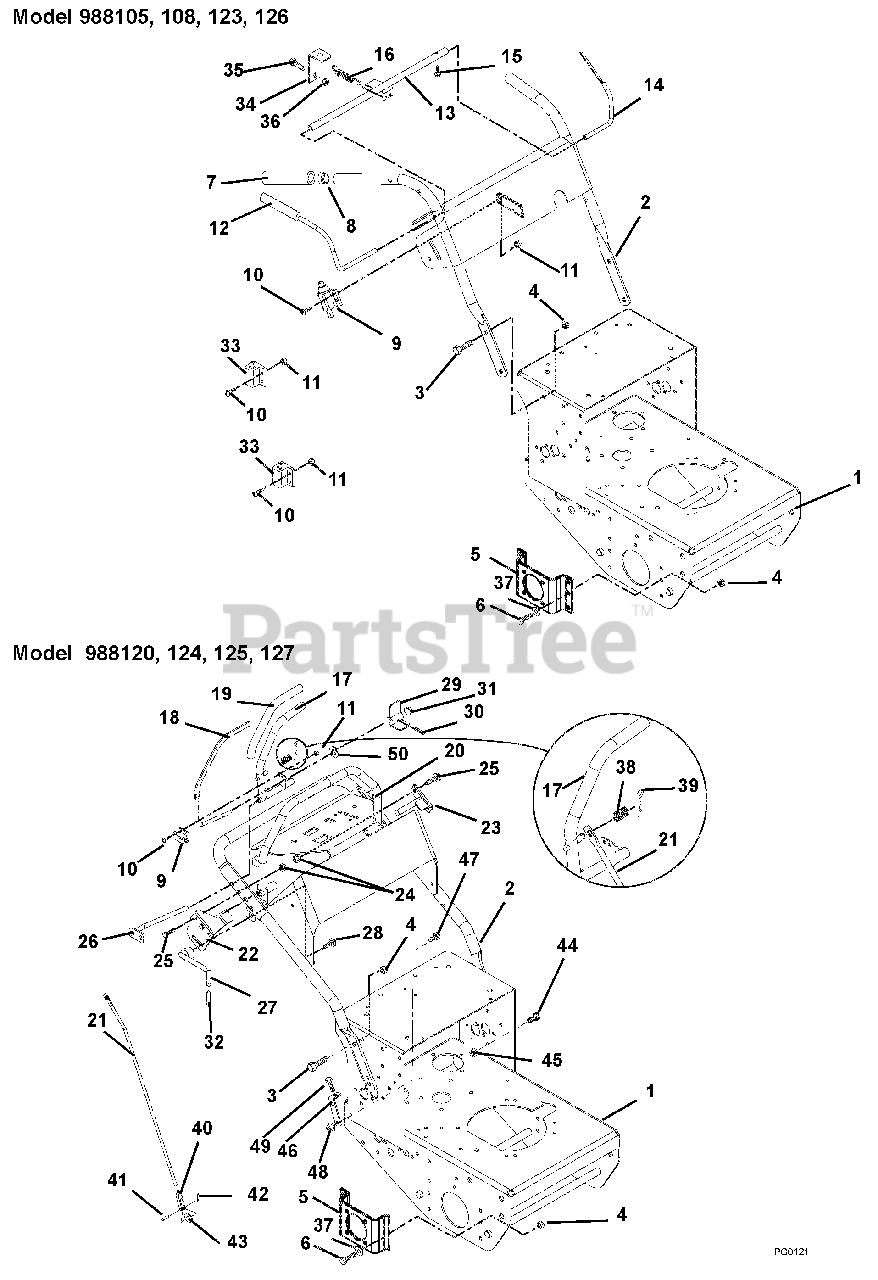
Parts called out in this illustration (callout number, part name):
1	Kit-Frame with Decals
2	Kit-Handlebar with Decals HR15 (105)
3	Bolt-Hex .38-16 x 1.00 Grade 5
4	Nut-Locking-Nylon .38-16
5	Bracket, Wheel Motor Left Hand (105, 108, 120, 124, 125)
6	Bolt-Hex .38-16 x 1.00 Grade 5
7	Grip, Handlebar (105, 108, 123, 126)
8	Caplug, Handlebar (105, 108, 123, 126)
9	Switch, Double Pole (105, 108, 123, 126)
10	Screw, Machine 10-24 x .75 Hex Washer Head (105, 108, 213, 126)
11	Nut-Locking-Nylon 10-24 with Insert (105, 108, 123, 126)
12	Lever, Right Hand-Operator Presence (105, 108, 123, 126)
13	Weldment, Pivot Tube (105, 108, 123, 126)
14	Lever, Left Hand-Operator Presence (105, 108, 123, 126)
15	Screw-Tapping 8-32 x .50 Hex Washer Head (105, 108, 123, 126)
16	Spring-Tension .047 x .438 x 1.45 (105, 108, 123, 126)
17	Weldment, Lever-Right Hand Speed Control (120, 124, 125, 127)
18	Lever- Operator Presence (120, 124, 125, 127)
19	Grip- Handlebar (120, 124, 125, 127)
20	Weldment- Speed Control Stop (120, 124, 125, 127)
21	Rod, Steering (120, 124, 125, 127)
22	Weldment, Control Stop Limiter-Right Hand (120, 124, 125, 127)
23	Weldment, Control Stop Limiter-Left Hand (120, 124, 125, 127)
24	Nut-Locking-Top-Flange .31-18 (120, 124, 125, 127)
25	Bolt-Hex .31-18 x 1.75 Grade 5 (120, 124, 125, 127)
26	Weldment, Speed Control Pivot- Right Hand (120, 124, 125, 127)
27	Lever- Control Stop Lock (120, 124, 125, 127)
28	Bolt-Round Head Square Neck .38-16 x .75 Grade 2 (120, 124, 125, 127)
29	Actuator, Switch (120, 124, 125, 127)
30	Pin-Roll .125 x .75 (120, 124, 125, 127)
31	Nut-Push .312 (120, 124, 125, 127)
32	Grip, Hand Clutch Lever (120, 124, 125, 127)
33	Switch- Double Pole N.O./N.O. (105, 108, 123, 126)
34	Bracket, Brake Link (105, 108, 123, 126)
35	Bolt, Hex .25-20 x .75 Grade 5 (105, 108, 123, 126)
36	Nut, Locking Nylon .25-20 (105, 108, 123, 126)
37	Washer, Flat Steel .406 x .812 x .065 (105, 108, 123, 126)
38	Spring-Compression .045 x .60 x .75 (120, 124, 125, 127)
39	Pin-Hair Internal .08 x .18 x 1.18 (120, 124, 125, 127)
40	Yoke, .312-24 x 2.25 (120, 124, 125, 127)
41	Pin-Clevis .31 x .937 (120, 124, 125, 127)
42	Pin-Hair, Endries #25 (120, 124, 125, 127)
43	Washer-Flat-Steel .38 x .87 x .179 (120, 124, 125, 127)
44	Bolt-Hex .31-18 x 1.00 Grade 5 (120, 124, 125, 127)
45	Nut-Spin Lock-Flange .312-18 (120, 124, 125, 127)
46	Weldment- Reverse Adjustment Bracket (120, 124, 125, 127)
47	Bolt-Hex .38-16 x .75 Grade 5 (120, 124, 125, 127)
48	Nut-Locking-Top-Flange .38-16 (120, 124, 125, 127)
49	Bolt-Hex .31-18 x 1.25 Grade 5 (120, 124, 125, 127)
50	Washer, Wave (120, 124, 125, 127)
